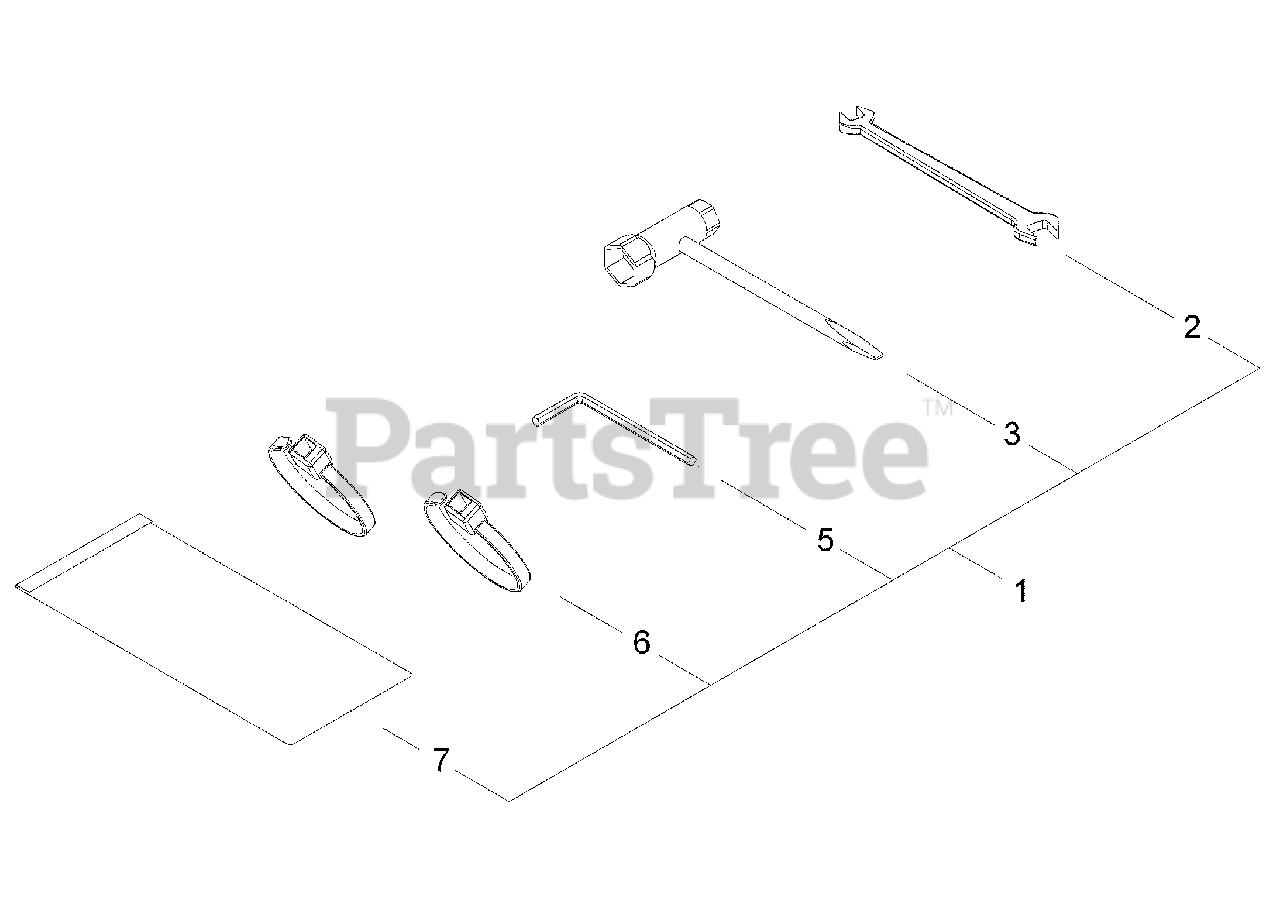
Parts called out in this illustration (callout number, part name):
1	TOOL KIT, SERVICE
2	SPANNER 8×10
3	T-WRENCH 16×13
5	WRENCH, ALLEN 4 MM
6	TIE, CABLE
7	BAG, TOOL
